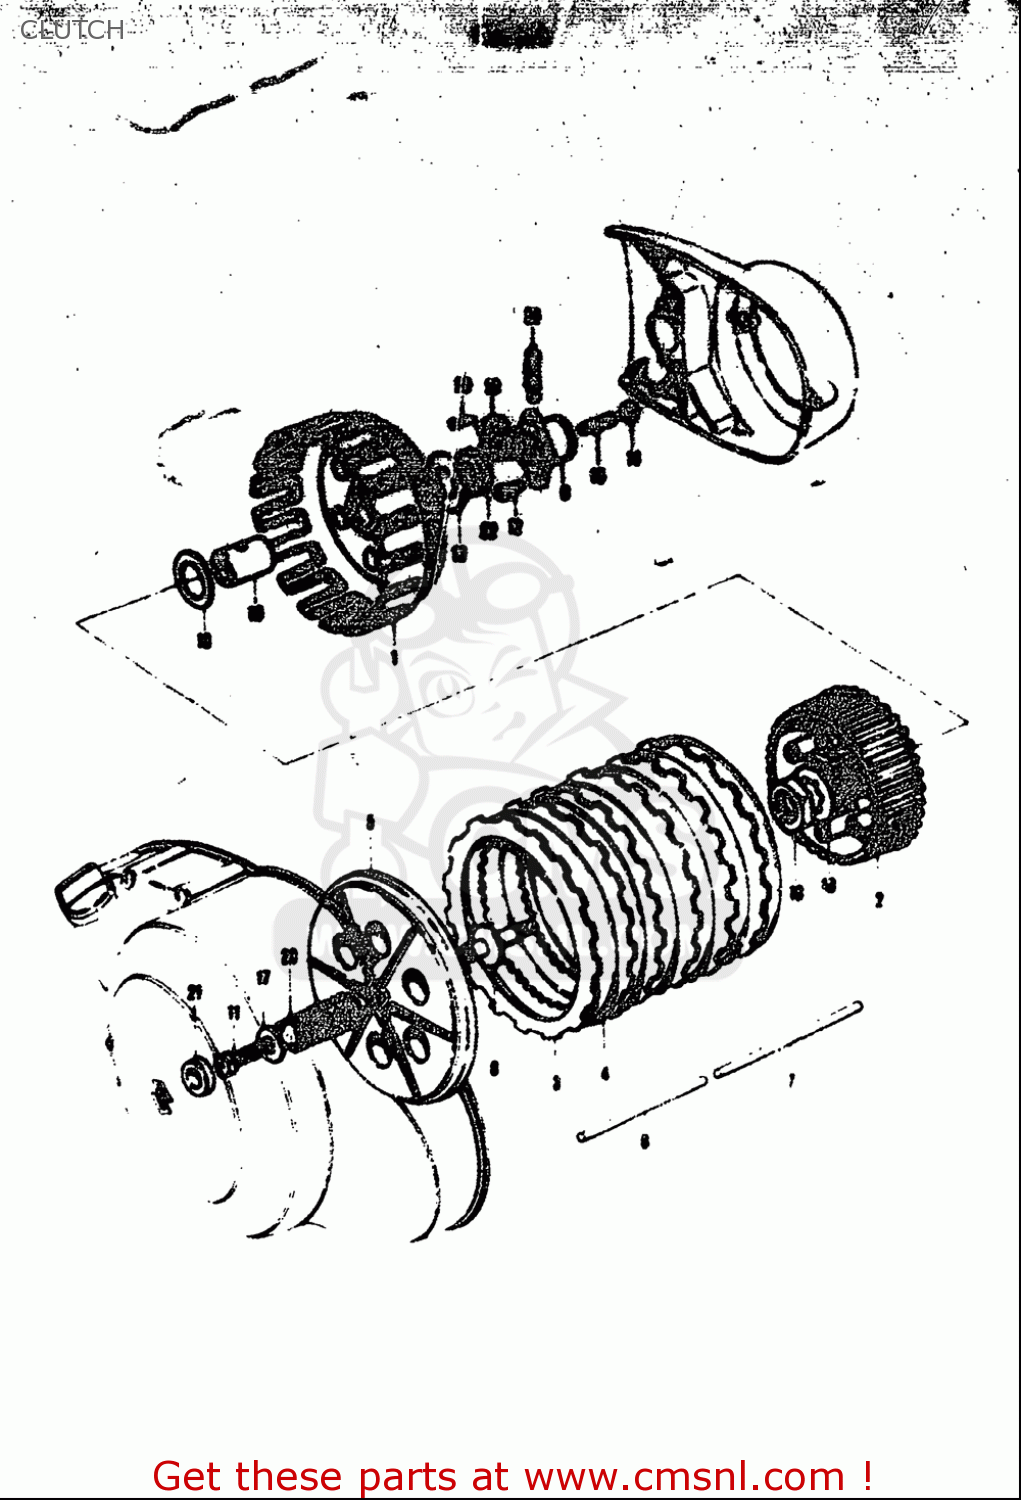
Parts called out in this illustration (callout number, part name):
4	PLATE,CLUTCH DRIVEN(T:2.0) (NAS)
6	ROD,CLUTCH PUSH
12	SCREW
13	WASHER(20X38X2)
14	NUT
15	SCREW(6X25)
16	NUT
17	WASHER(6.5X20X1.6)
18	WASHER,LOCK
19	SPACER,PRIMARY DRIVEN GEAR
21	SEAL,OIL (10X17X5)
22	SEAL,OIL (6X30X5)
23	SPRING
24	SPRING
